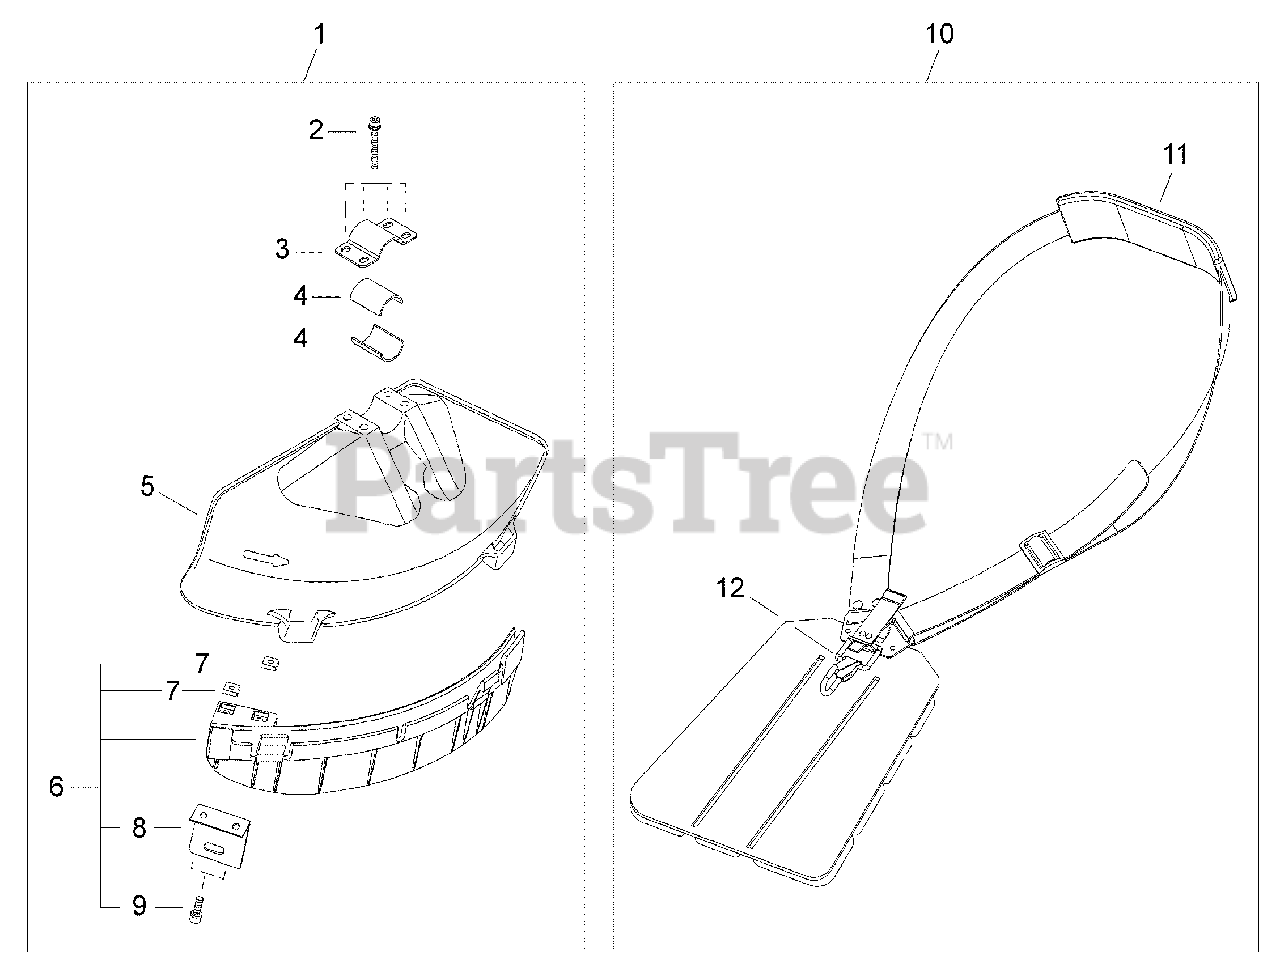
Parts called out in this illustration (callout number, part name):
1	DEBRIS SHIELD KIT
2	BOLT M5×45
3	CLAMP, UPPER
4	SPACER 26
5	SHIELD, DEBRIS PLASTIC
6	DEBRIS SHIELD EXTENSION ASSY
7	NUT M5
8	CUTTER
9	BOLT M5×16
10	HARNESS ASSY, BRUSHCUTTER
11	PAD, SHOULDER
12	HOOK, SNAP
